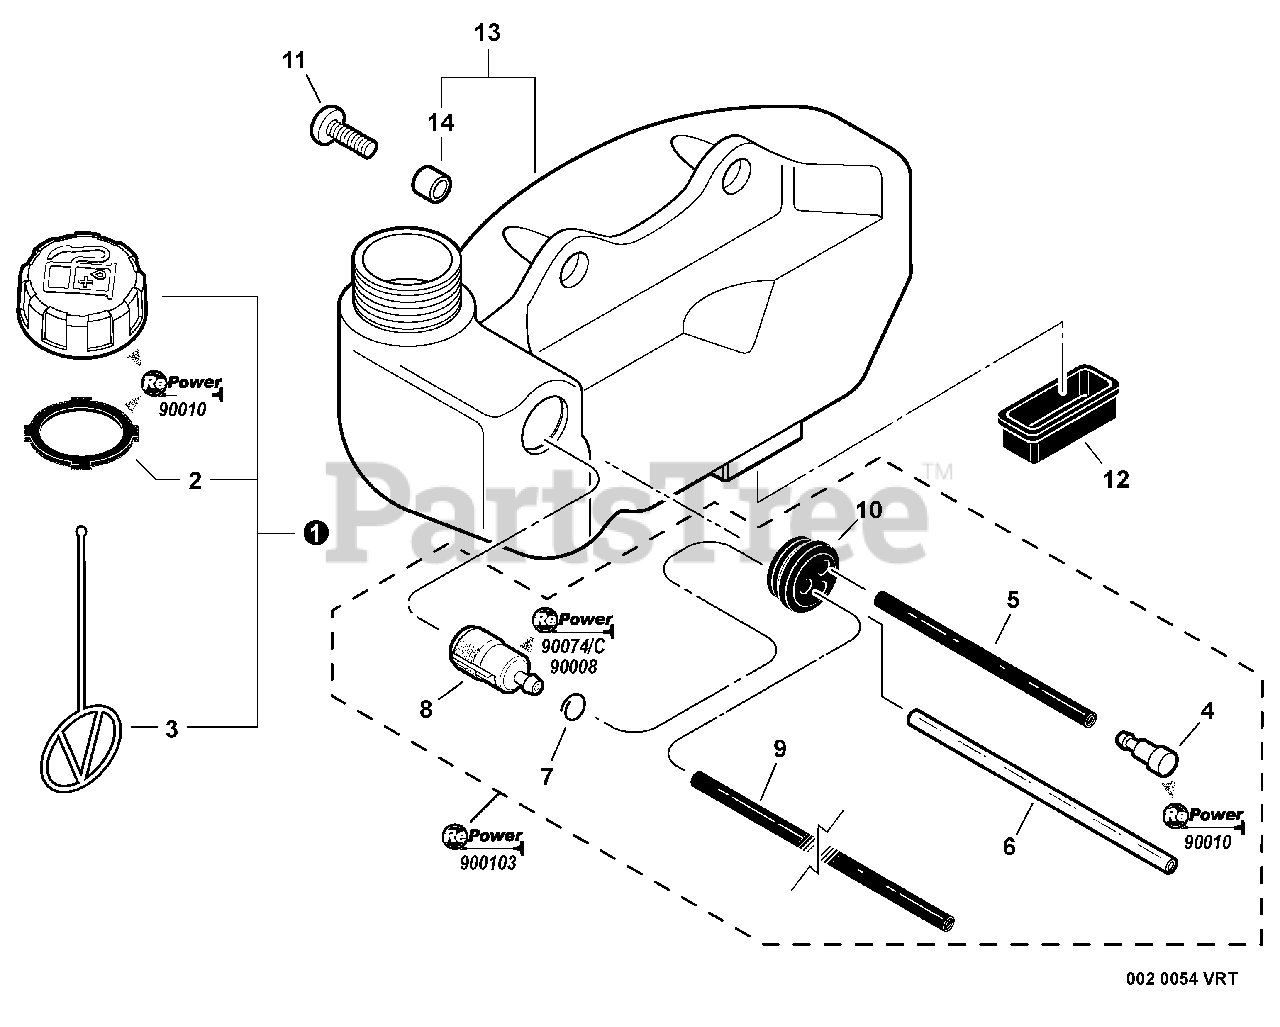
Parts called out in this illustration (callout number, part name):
1	CAP ASSY, FUEL
2	GASKET, FUEL CAP
3	CONNECTOR, CAP L= 100 MM
4	VENT ASSY
5	PIPE, FUEL 3x-5x-70 BLACK
6	PIPE, FUEL RETURN 3×6×110
7	CLIP Ø6
8	FILTER, FUEL
9	PIPE, FUEL 3×5×195 BLACK
10	GROMMET, FUEL
11	SCREW 5×15
12	CUSHION, FUEL TANK
13	TANK ASSY, FUEL
14	SPACER 6.2×7.8×6
15	FUEL SYSTEM KIT
16	TUNE-UP KIT - REPOWER
17	FILTER KIT - REPOWER
18	CAP/VENT KIT - REPOWER
